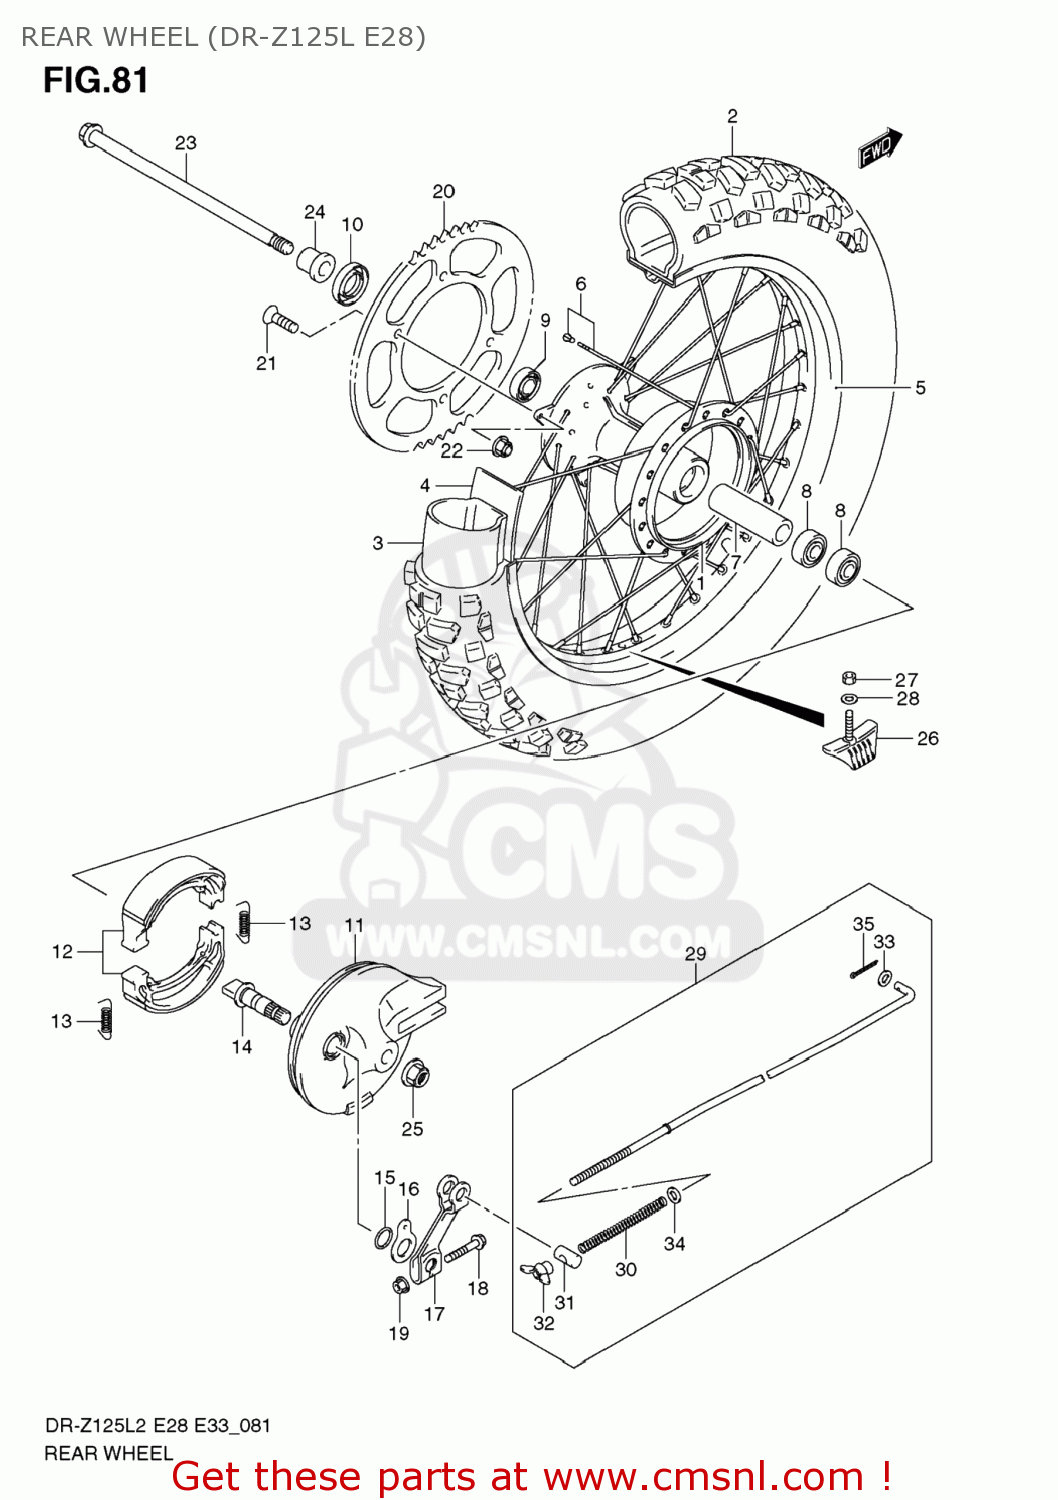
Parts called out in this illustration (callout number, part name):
1	HUB,RR WHEEL
2	TIRE,RR
3	TUBE ASSY,WHEEL INNER
4	PROTECTOR,WHL INR TUBE
5	RIM,RR WHEEL(16X1.60)
6	SPOKE SET,RR WHEEL
7	SPACER(12.5X19X45.5)
8	BEARING
9	BEARING
10	SEAL,OIL(20X37X7)
11	PANEL,RR BRAKE ANCHOR
12	SHOE SET,BRAKE (NAS)
13	SPRING
14	CAM,RR BRAKE
15	O RING(D:2.5,ID:13.8)
16	PLATE,BRAKE LINING INDICATOR
17	LEVER,RR BRAKE CAM
18	BOLT
19	NUT
20	SPROCKET,RR(57T-428)
21	BOLT(8X30.5)
22	NUT
23	AXLE,RR
24	SPACER,RR AXLE
25	NUT
26	STOPPER,BEAD
27	NUT
28	WASHER
29	ROD ASSY,RR BRAKE
30	SPRING
31	PIN(11X18)
32	NUT
33	WASHER
34	WASHER
35	PIN
